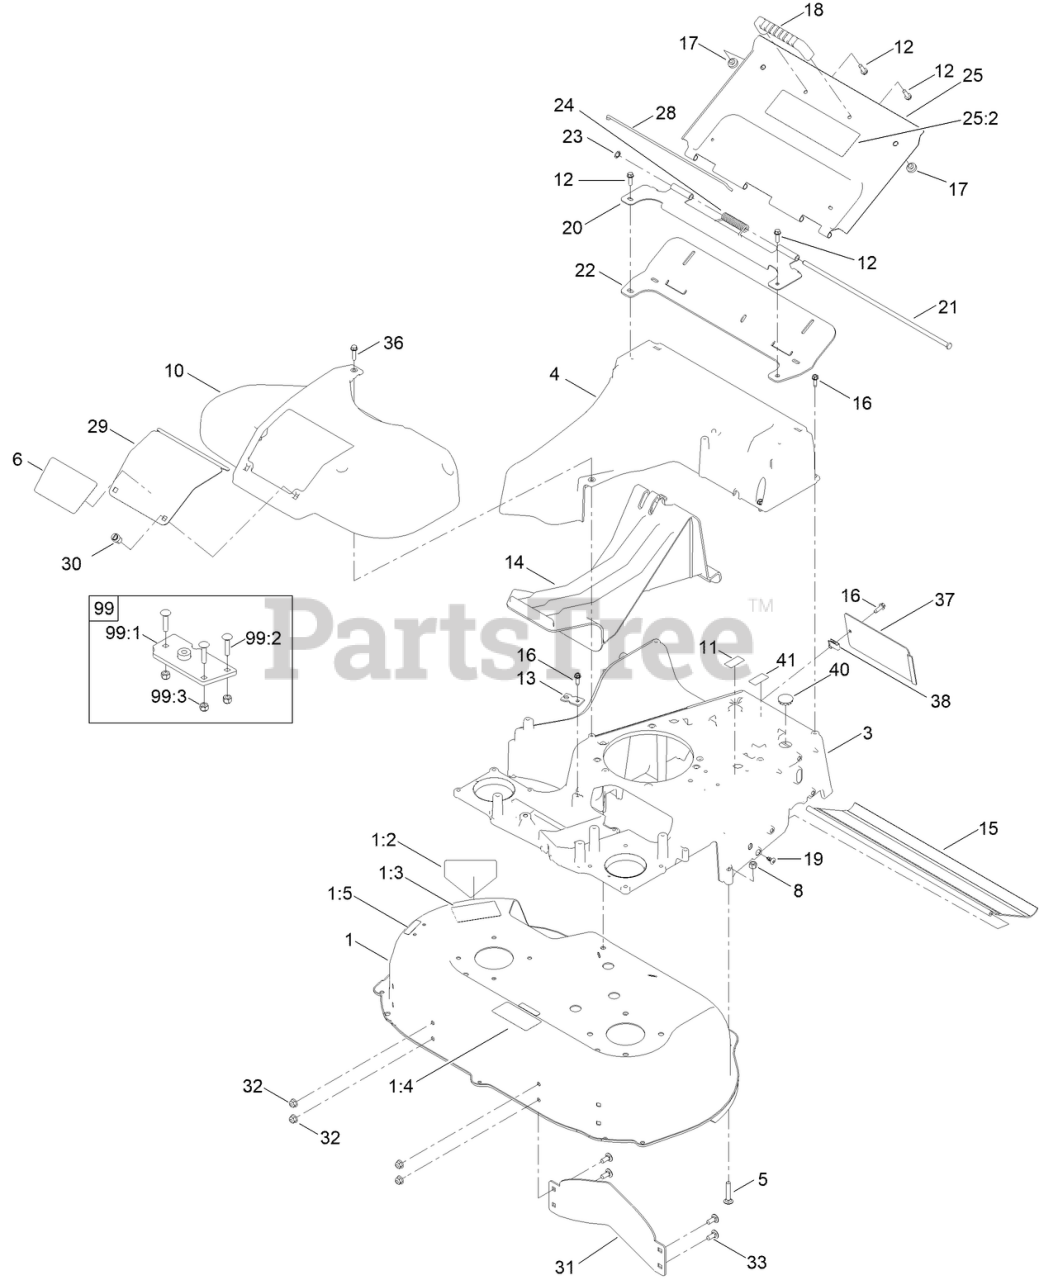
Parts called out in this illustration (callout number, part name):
1	DECK ASM
1:2	DECAL-DANGER
1:3	DECAL-DANGER, CE
1:5	DECAL-WARNING
3	FRAME-30 INCH
5	BOLT-CAR
6	DECAL-30 INCH
8	NUT-LOCK, NI
10	COVER-BELT
11	DECAL-PATENT
12	SCREW-HWH
13	BRACKET-CABLE, TRACTION
14	PLUG-MULCH
15	SHIELD-TRAILING
16	SCREW-HWHTF
17	BUMPER
18	HANDLE-DOOR
19	SCREW-PTH
20	BRACKET-HINGE
21	PIN-HINGE
22	SEAL-DOOR
23	RING-RETAINING
24	SPRING-TORSION, COVER
25	REAR DOOR ASM
25:2	DECAL-WARNING
28	CLIP-SEAL
29	DOOR-ACCESS
30	FASTENER
31	BAFFLE-CONTROL
32	NUT-HF, NI
33	SCREW-CARR
36	SCREW-HWHTF
37	COVER-FRAME
40	PLUG-BUTTON
41	DECAL-ARRESTOR, SPARK
99	FRAME PLATE KIT
99:1	PLATE-FRAME
99:2	SCREW-CARR
99:3	NUT-LOCK, NI
